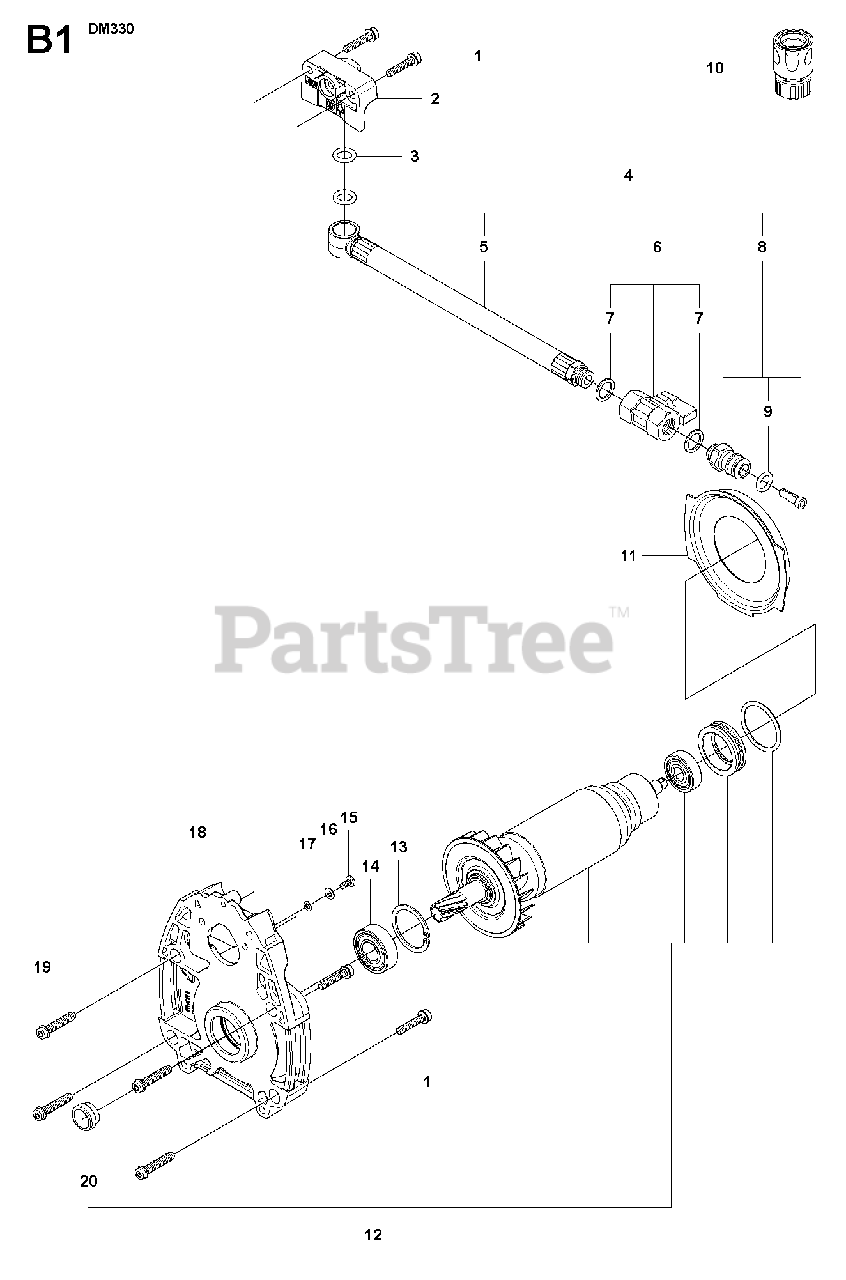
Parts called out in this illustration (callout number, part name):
1	SCREW IHSCFM
4	HOSE ASSYincl 5,6,7,8,9
6	VALVE KITincl 7
8	NIPPLEincl 9
10	COUPLERUSA, CANADA
14	BALL BEARING
15	SCREW CRPANM
